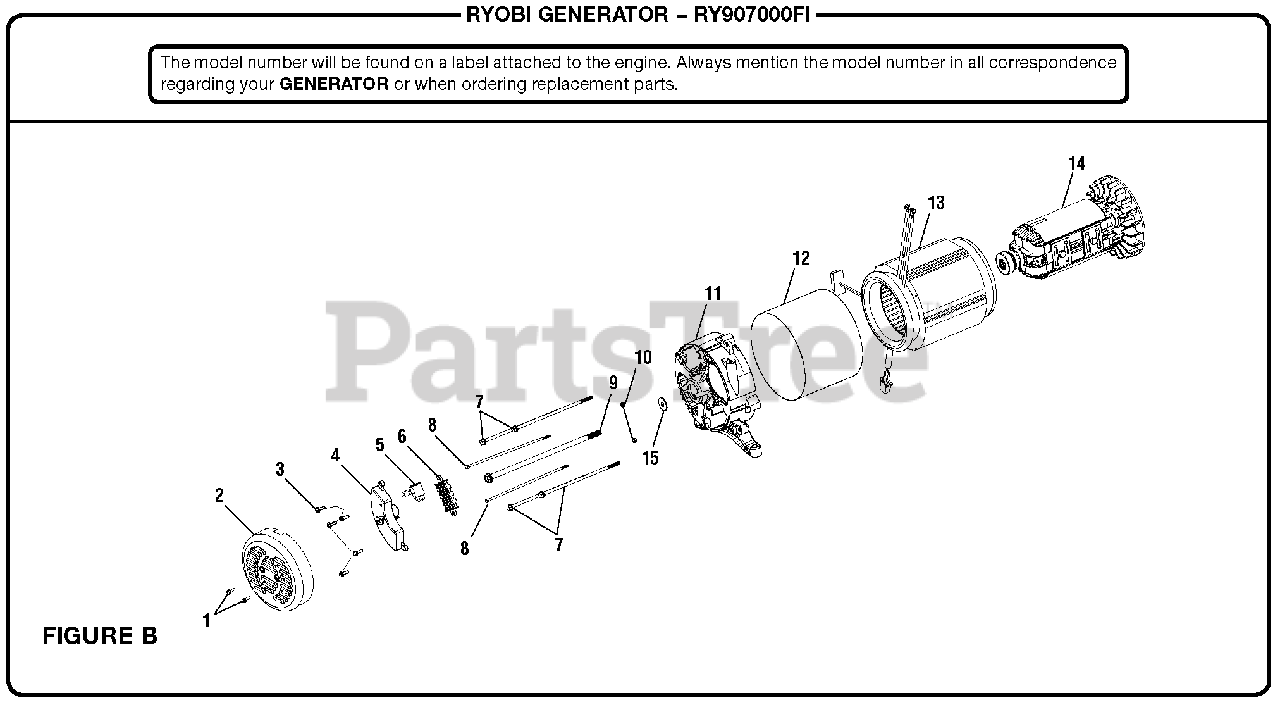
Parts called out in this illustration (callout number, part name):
1	Bolt (M5 x 12 mm, Hex Flange Hd.)
2	Brush Cover
3	Bolt (M5 x 16 mm, Hex Flange Hd.)
4	Automatic Voltage Regulator
5	Brush Assembly 190 mm
6	Terminal Block
7	Stator Bolt
8	Bolt (M6 x 229mm)
9	Bolt (M10 x 280 mm)
11	Bearing Housing
13	Stator Assembly
14	Rotor Assembly
15	Rotor Washer
